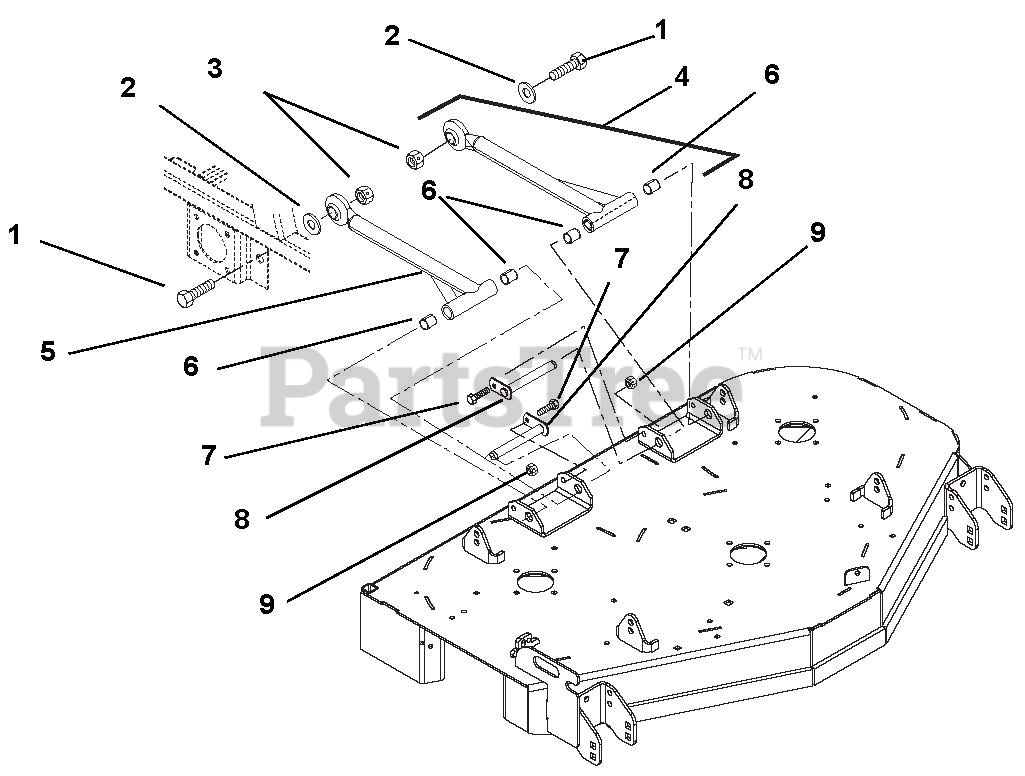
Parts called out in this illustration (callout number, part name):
1	Bolt, Hex .875-9 x 3.00
2	Bushing, Sleeve .875 x 1.250 x .531
3	Nut, Locking Center .875-9
4	Assembly, Mower Mounting
5	Mower Mounting Arm
6	Bearing, .75 x .875 x 1.00
7	Bolt-Hex .38-16 x 1.00 Grade 5
8	Weldment, Mower Mounting Pin
9	Nut, Nyloc Flange 3/8-16
